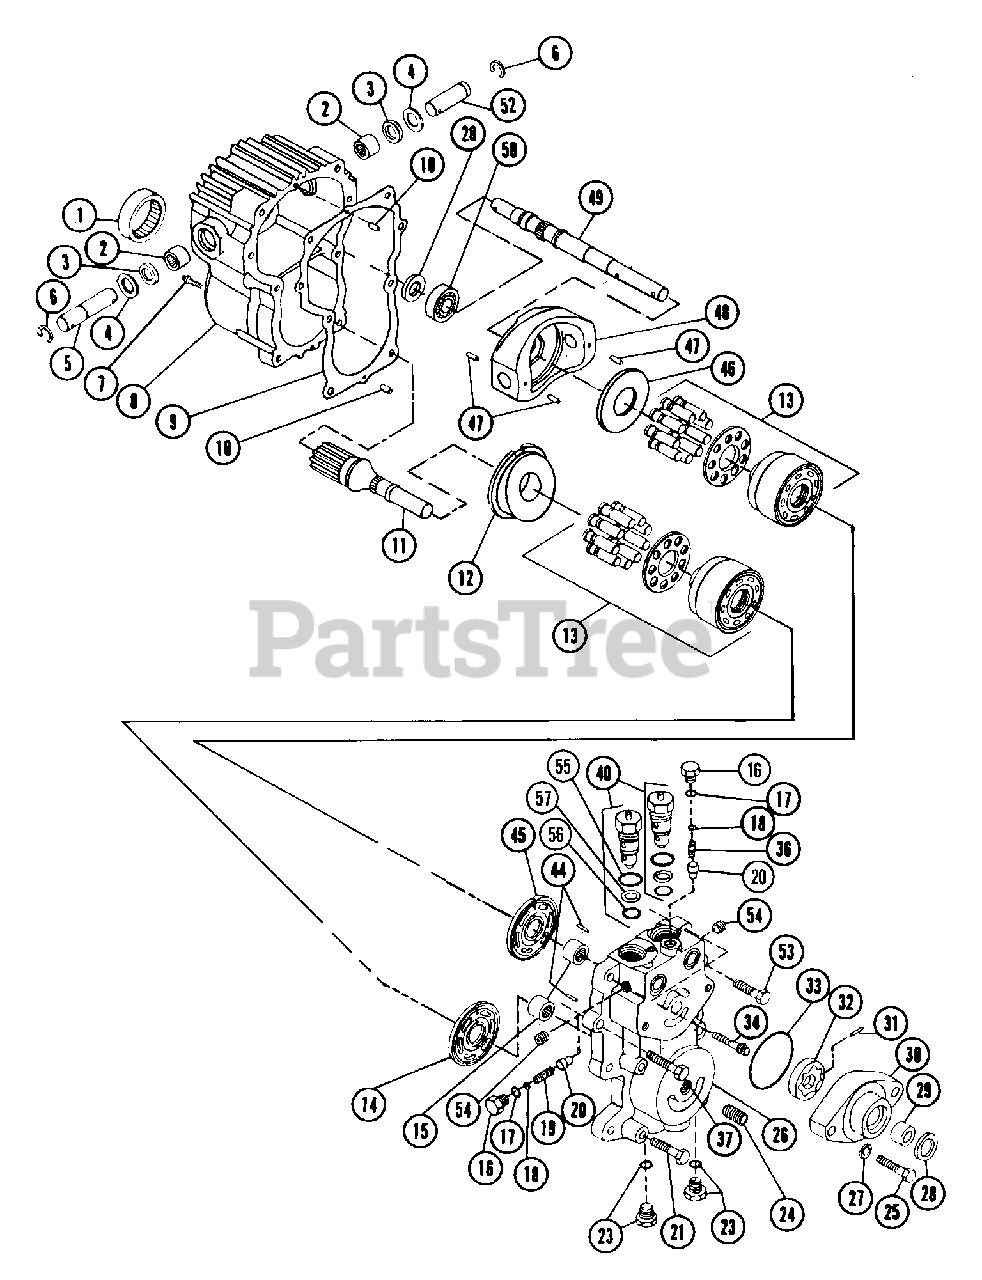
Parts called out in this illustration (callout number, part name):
1	BRG-ROLLER 1.27X2.05X15MM
2	BRG-NEEDLE .688X.876X.63
3	SEAL .625X1.187X.187
4	WSHR-FL-STL .699X1.375X.059
5	TRUNNION SHAFT
6	RG-RTNG-EXT .688X.042
7	SCR-12PNT .25-20X.88 GR5
8	HOUSING
10	DOWEL PIN
11	MOTOR SHAFT
12	SWASH PLATE
13	CYLINDER BLOCK KIT
14	MOTOR VALVE PLATE
15	BRG-NEEDLE 17MMX.938X.62
16	PLUG-HEX HEAD
17	O-RING .414X.562X.072
18	SHIM PACKAGE
19	SG-COMP ??X??X?? SUNSTRAND
20	RELIEF VALVE CONE
21	BLT-HEX .38-16X2.00 PL GR5
23	THREADED PLUG
25	BLT-HEX .44-14X2.00 GR5
26	CENTER SECTION
27	WSHR-FL-STL .469X.719X.108
28	SEAL .625X1.128X.250
29	BRG-NEEDLE .625X.875X.50
30	CHARGE PUMP HOUSING
31	DOWEL PIN
32	ROTOR ASSEMBLY
33	O-RING 2.364X2.504X.072
34	SCR-12PNT .38-16X1.25 GR5
36	SG-COMP SUNSTRAND
37	BLT-HEX .38-16X1.25 PL GR5
40	CHECK VALVE ASSEMBLY
44	DOWEL PIN
45	PUMP VALVE PLATE
46	THRUST PLATE
47	PIN-ROLL .188X.63
48	SWASH PLATE
49	PUMP SHAFT
50	BRG-BALL 17MMX40MMX12MM
52	TRUNNION SHAFT
53	BLT-HEX .38-16X1.50 PL GR5
54	PIPE PLUG
55	O-RING .770X.968X.097
56	O-RING .614X.750X.070
57	O-RING .614X.750X.046
